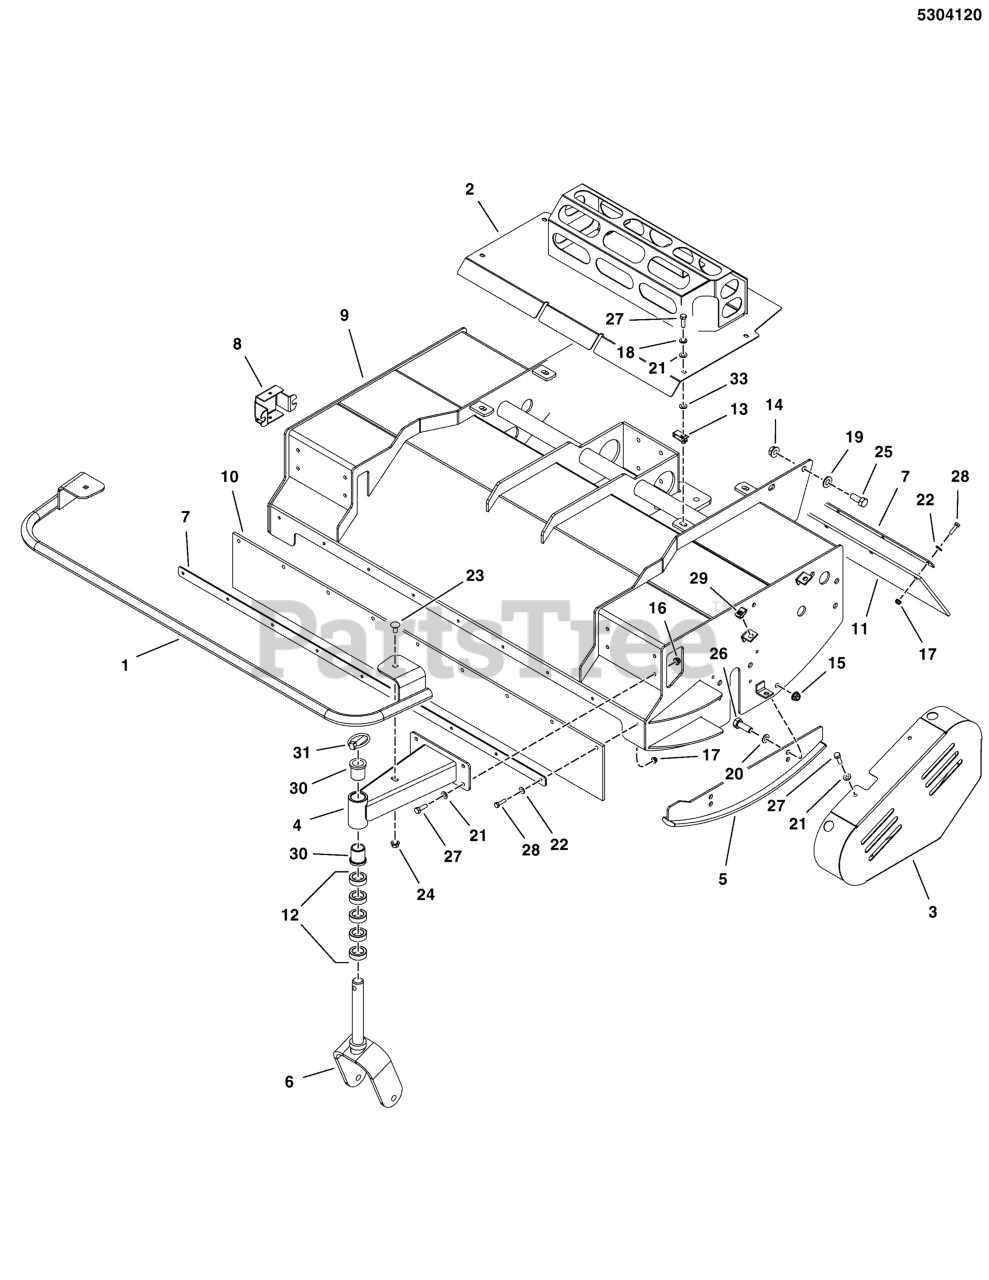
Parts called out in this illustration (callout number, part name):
1	WELD, GUARD, BRUSH - RED
2	WELD, GUARD, MUFFLER, FLAIL - RED
3	WELD, GUARD, PULLEY - RED
4	WELD, CASTER ARM, FLAIL - RED
5	WELD, SKID, FLAIL - RED
6	WELD, CASTER WHEEL MOUNT - RED
7	BAR, RUBBER RETAINING - RED
8	GUARD, BEARING - RED
9	WELD, 48-HOOD, FLAIL - RED
10	RUBBER, FRONT SKIRT, 48 FLAIL
11	RUBBER, REAR SKIRT, 48 FLAIL
12	SPACER, 1.02 X 1.56 X .50
13	BODY CLIP, 5/16-18 -1/4 MATERIAL
14	NUT, Hex Flange, Nylock, 1/2-13
15	NUT, 3/8-16 HEX NYLOCK FLANGE
16	NUT, 5/16-18 HEX NYLOCK FLANGE
17	NUT, 1/4-20 HEX NYLOCK FLANGE
18	WASHER, 5/16 LOCK CZ
19	WASHER, 1/2 SAE
20	WASHER, 3/8 SAE
21	WASHER, 5/16" SAE
22	WASHER, 1/4 SAE
23	BOLT, 3/8-16 X 3/4, CARRIAGE
24	NUT, 3/8-16 HEX SERRATED FLANGE
25	BOLT, 1/2-13 X 1-1/4 GD5 CZ
26	BOLT, 3/8-16 X 1" GD5 CZ
27	BOLT, 5/16-18 X 1 GD5 YZ
28	BOLT, 1/4-20 X 1" GD5 CZ
29	BODY CLIP, 5/16-18-7GA MATERIAL
30	BUSHING, FLANGE
31	PIN, LYNCH, 7/16
33	5/16 PUSH-ON NUT RETAINER, STL, CZ
